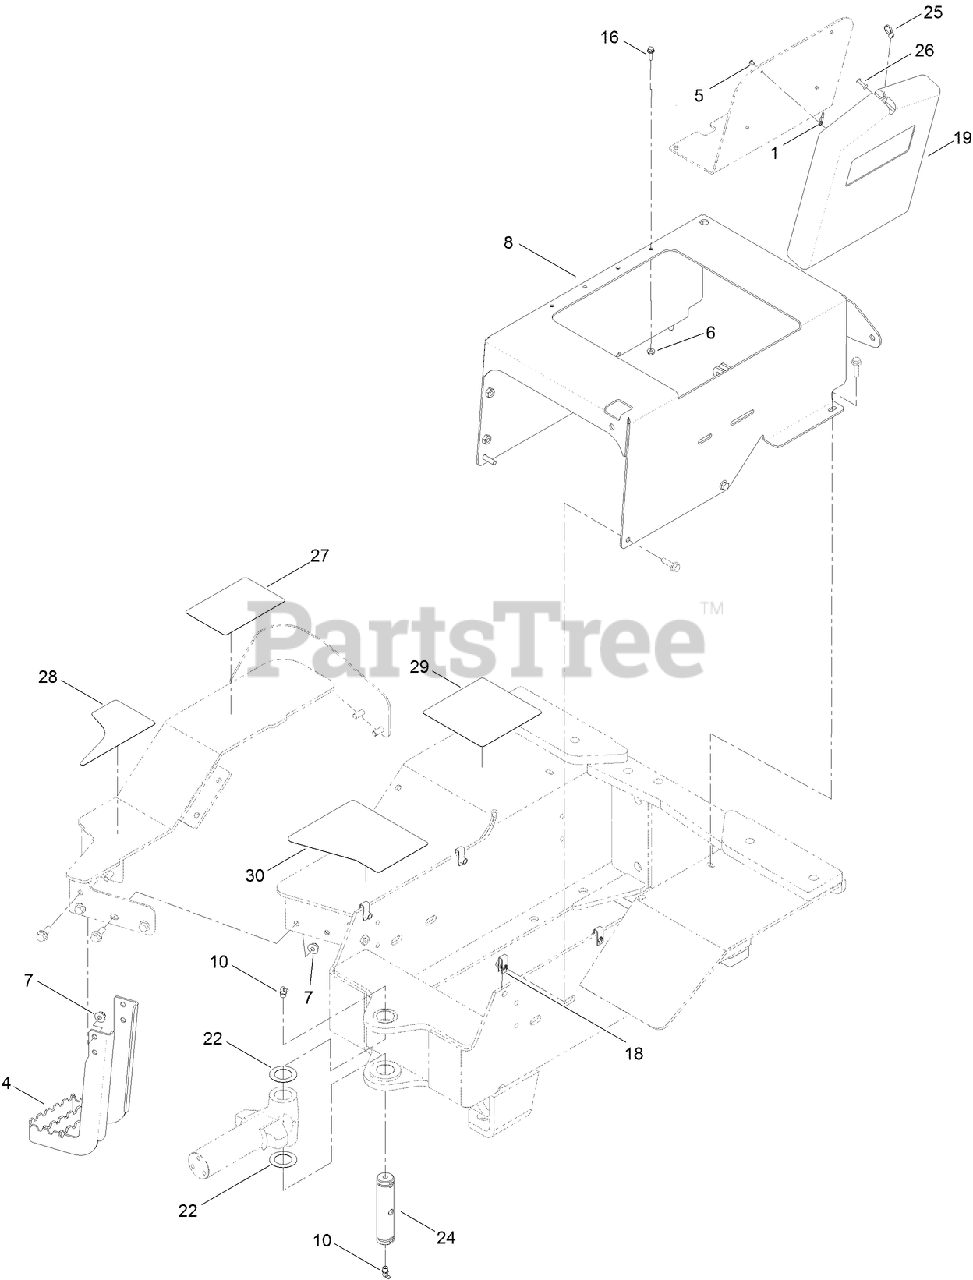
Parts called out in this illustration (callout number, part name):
1	LANYARD
4	STEP-PLATFORM
5	RIVET-POP
6	NUT-HF
7	NUT-HF, NI
8	SUPPORT-SEAT
10	FITTING-GREASE
16	SCREW-HHF
19	HOLDER-MANUAL, OPERATOR
24	PIN-PIVOT
25	STRAP-TIE, NYLON
26	POST-MANUAL
27	TREAD-FLOORBOARD
28	TREAD-FLOORBOARD
29	TREAD-FLOORBOARD
30	TREAD-FLOORBOARD
